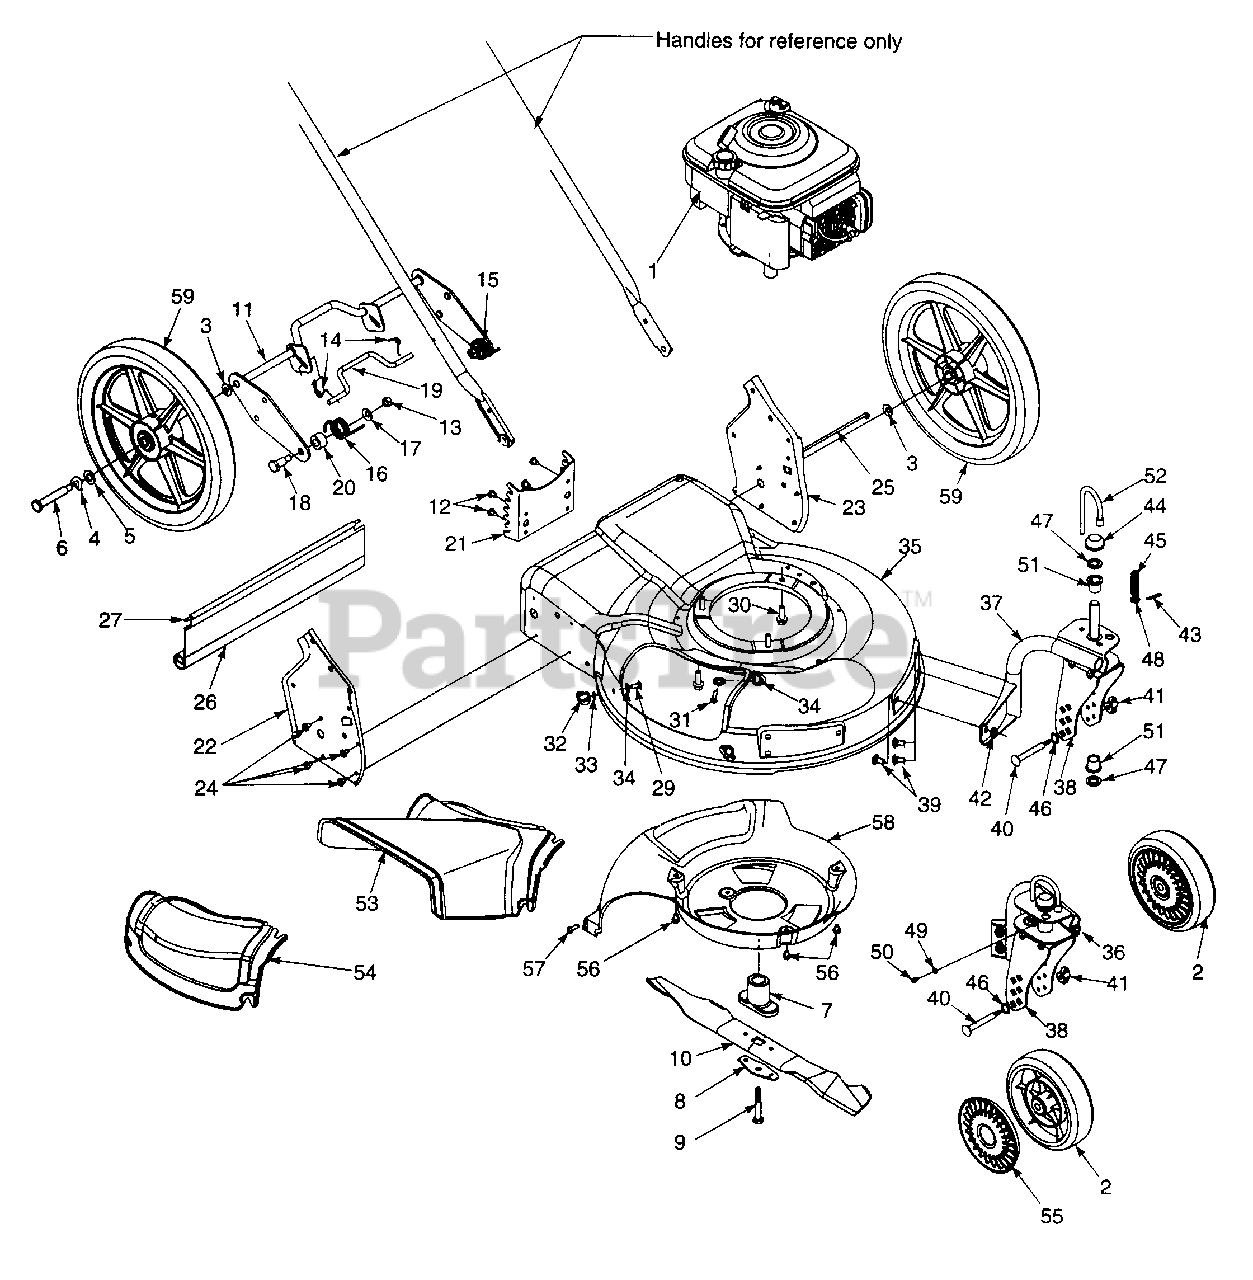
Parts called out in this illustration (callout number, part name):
1	Engine
2	Wheel, Front Caster 7 X 2
3	Bell Washer .401 X .870 X .063
4	Spring Washer.50 I.D. x 1.0 O.D. x .022
5	Flat Washer .510 x 1.0 x .060
6	Shoulder Screw .500 x 2.62: 3/8 -16
7	Blade Adapter
8	Blade Bell Support
9	Hex Bolt 3/8 - 24 x 2.5 Gr. 8
10	Blade 21", Mulching
11	Hi-wheel Height Adj. Support
12	AB Screw 1/4-14 x .50
13	Hex Nut 3/8 -16
14	Torsion Spring
15	Torsion Spring, RH
16	Torsion Spring, LH
17	Bell Washer .401 x .870 x .063
18	Shoulder Screw .500 x .840
19	Handle, Height Adjustment
20	Spacer .500 x 1.0 x .600
25	Cable Tie
26	Trail Shield
27	Trail Shield Wire
29	Carriage Screw 1/4-20 x .62 Gr. 2
30	TT Screw 3/8-16 x 1.00
31	Carriage Screw 1/4-20 x .75
32	Wing Nut
33	Push Nut
34	Flat Washer
39	Carriage Bolt 5/16-18 x .62
40	Caster Axle .374 x 2.59
41	Wing Nut
42	Flange Nut 5/16-18 Gr.5
43	Hairpin Clip
44	Push Cap
45	Compression Spring
46	Wave Washer .530 I.D. x .780 O.D.
47	Wave Washer .530 I.D. x .780 O.D.
48	Flat Washer .330 I.D. x .630 x .06
49	Fl. Wash. .203 I.D. x .403 x .040
50	Lube Fitting
51	Flange Bearing
52	Lock Pin, Front Wheel
53	Discharge Chute
54	Mulching Cover
55	Hubcap
56	Hex Screw, TT 1/4-20 x .375
57	HL Screw
58	Rear Baffle
59	Hi-Wheel 14 X 2
